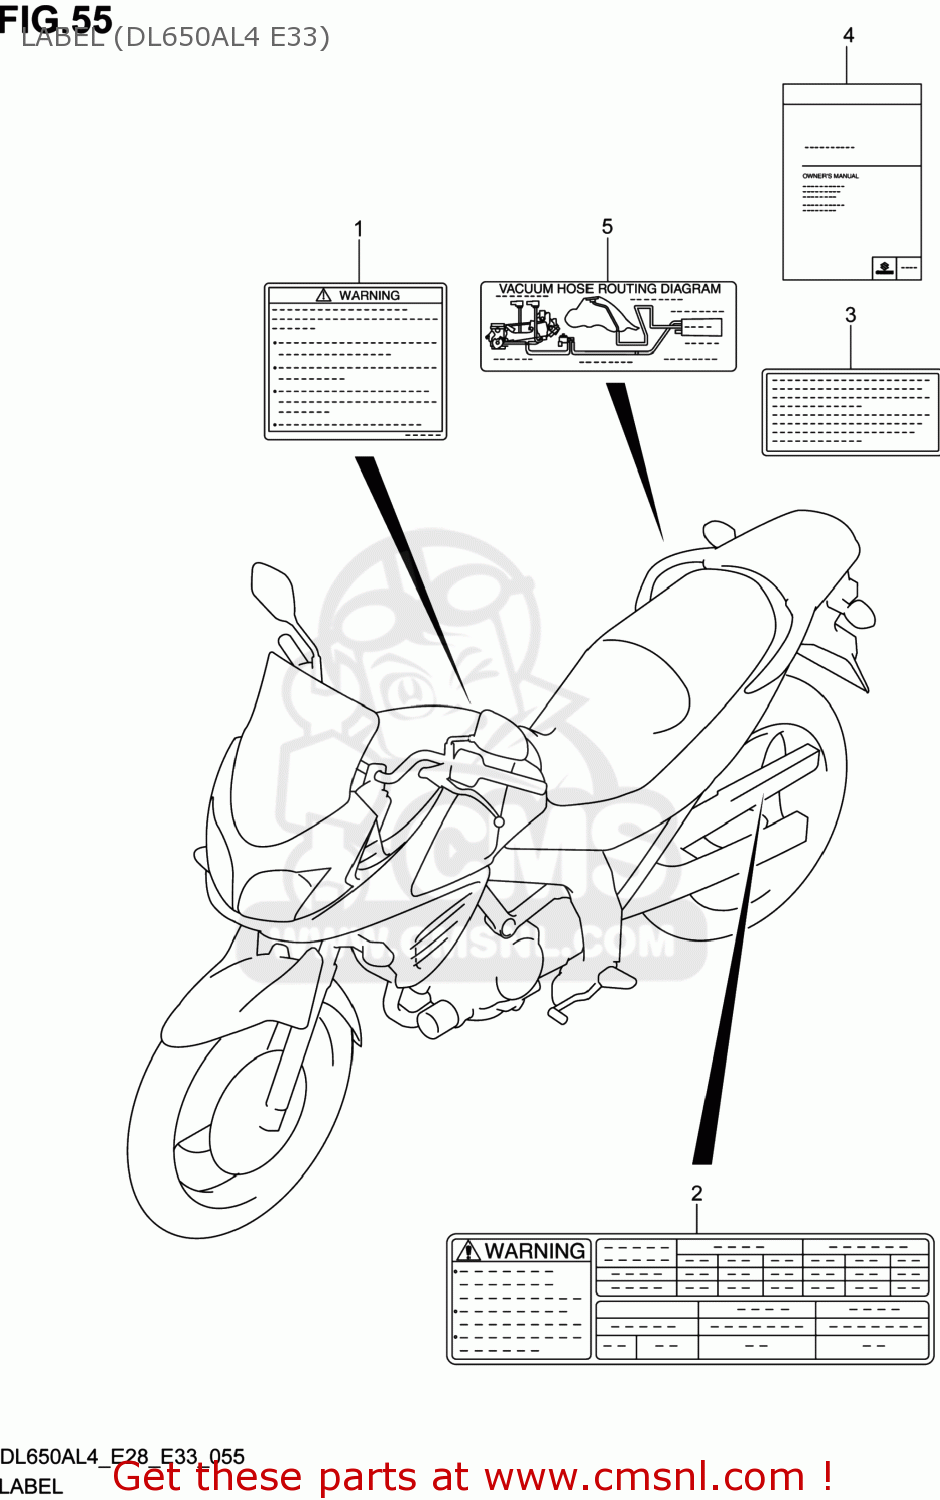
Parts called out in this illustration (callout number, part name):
1	LABEL,GENERAL WARNING
2	LABEL,TIRE INFORMATION
3	LABEL,MANUAL NOTICE
4	MANUAL,OWNER'S
5	LABEL,VACUUM HOSE ROUTING
